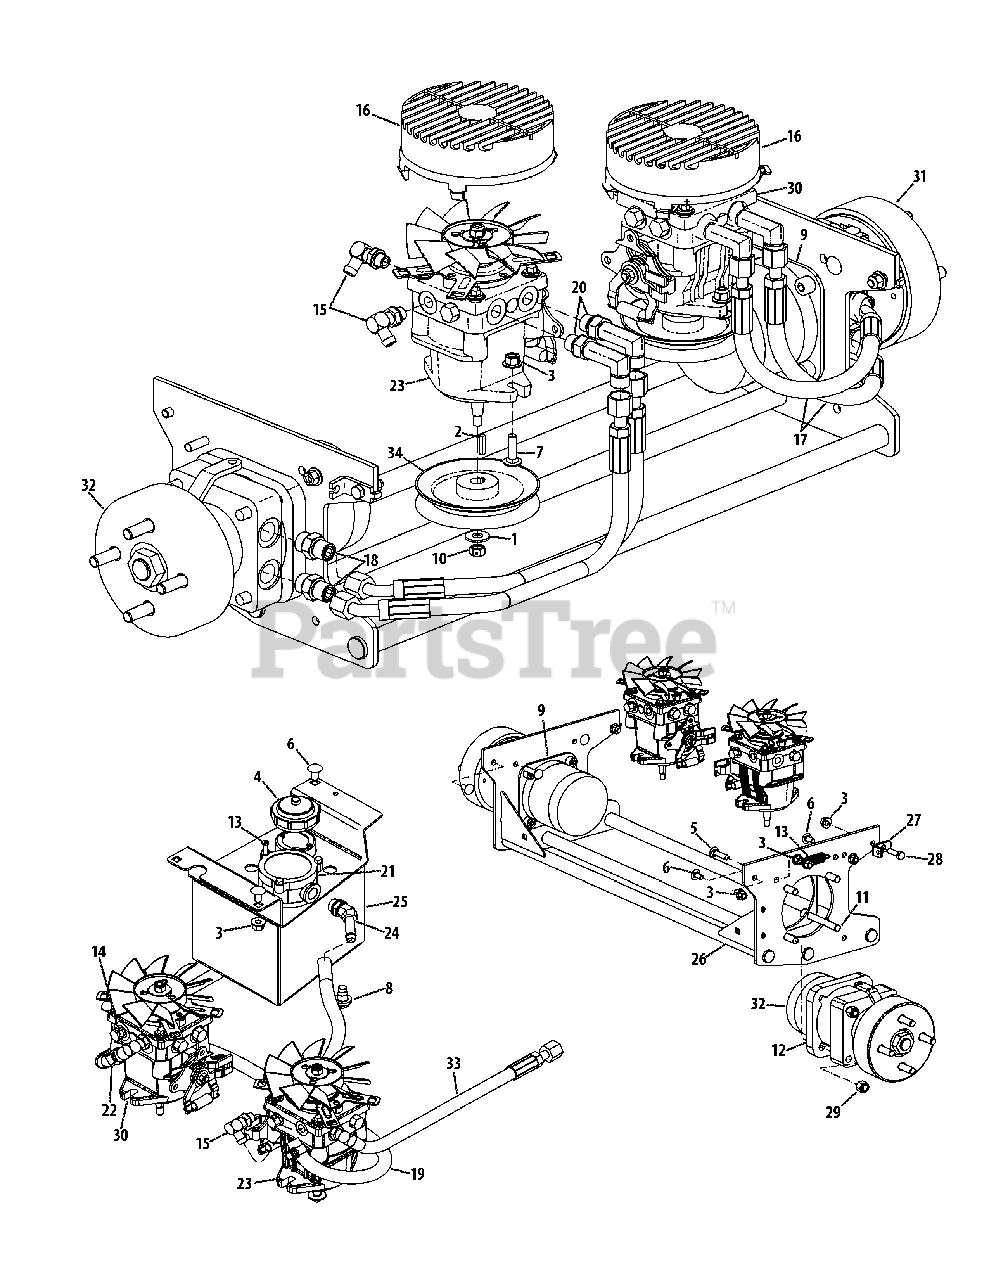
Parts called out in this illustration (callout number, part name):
1	Washer, .438 x 1.00 x .078
2	Key, .188 x .188 x .875
3	Flange Counter Lock Nut, 3/8-16
4	Hydro Oil Tank Cap
5	Carriage Bolt, 3/8-16 x 1.50
6	Carriage Bolt, 3/8-16 x .75
7	Carriage Bolt, 3/8-16 x 1.25
8	Oil Drain Plug, w/ Seal
9	Motor Back-Up Plate
10	Counter Lock Nut, 3/8-24
11	Socket Cap Screw, 1/2-13 x 3.50
12	Hydro Wheel Motor Spacer
13	Extension Spring, .74 x 2.7 x .075
14	Socket Cap Screw, 1/4-20 x .750
15	Elbow Fitting, 9/16 x 1/2
16	Pump Fan Shroud
17	Pump Moter Hose Assembly
18	Hydro Adapter, 8 x 10
19	Pilot Hydro Hose Assembly
20	Elbow Hydro Adapter, 8 x 8
21	Hydro Filter
22	Hose Clamp
23	RH Hydro Pump
24	Fitting, 3/4 x 1/2
25	Hydro Tank Assembly
26	Wide Motor Frame
27	Brake Cable Bracket
28	Hex Screw, 3/8-16 x 1.25
29	Hex Lock Nut, 1/2-13
30	LH Hydro Pump
31	LH Hydro Motor w/ Brake
32	RH Hydro Motor w/ Brake
33	Hose Assy. (Wheel Pump-Manifold)
